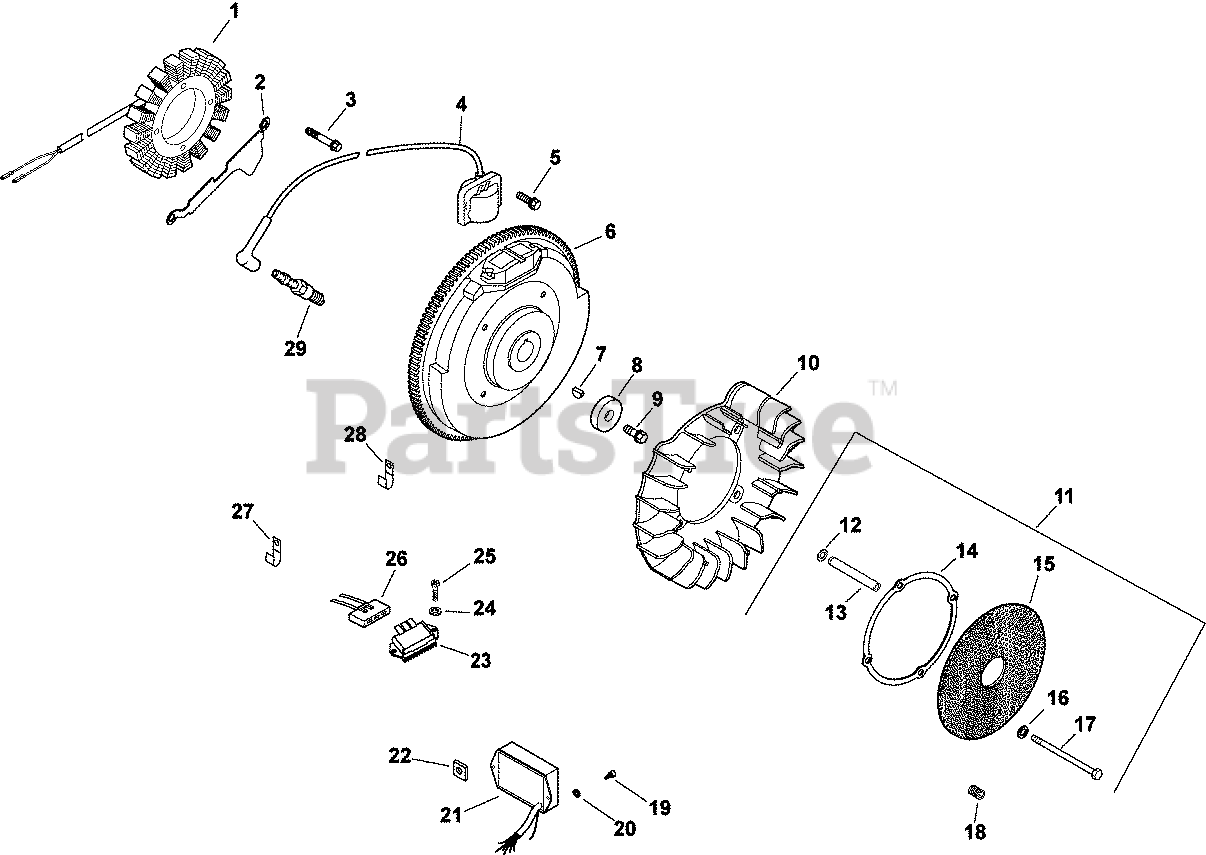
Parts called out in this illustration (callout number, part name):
1	KIT, 15 / 20 AMP STATOR
2	BRACKET, STATOR WIRE
3	SCREW, M5X0.8X25 - (#25086402S)
4	MODULE,IGNITION
5	SCREW, SKT THD FRM M5X0.8X25
6	FLYWHEEL ASSEMBLY - USE 24 025 14-S
7	KEY, 3/16" X 5/8"
8	WASHER, FLAT 13/32"
9	SCREW, FLG M10X1.5X45 - (#25086361S)
10	FAN (WITH HOLE)-USE 24 157 16-S
11	KIT, CHOPPER SCREEN
12	WASHER, SPRING 10 MM
14	RING, SUPPORT USE 25 141 08-S
15	SCREEN, GRASS
16	WASHER, FLAT 1/4" (O.D. 5/8")
17	SCREW, CAP M6X1.0X99.5
18	SCREW, SKT SET #10-24X1/4"
19	SCREW, PHL HD #11-16X1/2"
20	WASHER, FLAT 1/4" (O.D. 1/2")
21	MODULE, SPEED ADVANCE
22	NUT, PLASTIC
23	REG/RECT-15 AMP (KM)-USE 41 403 10-S
24	WASHER, FLAT 3/16"
25	SCREW, PHL HD #11-16X7/8"
26	CONNECTOR, BODY (KM)-USE 25 155 41-S
28	CLIP, CABLE
29	PLUG, SPARK (PRO SERIES)
2417616-S	HARNESS, WIRING
2508627-S	SCREW, VALVE
2545403-S	TIE, WIRE
4103710-S	NAMEPLATE, SERVICE
24126137-S	BRACKET, GROUND STRAP USE 24 518 12-S
